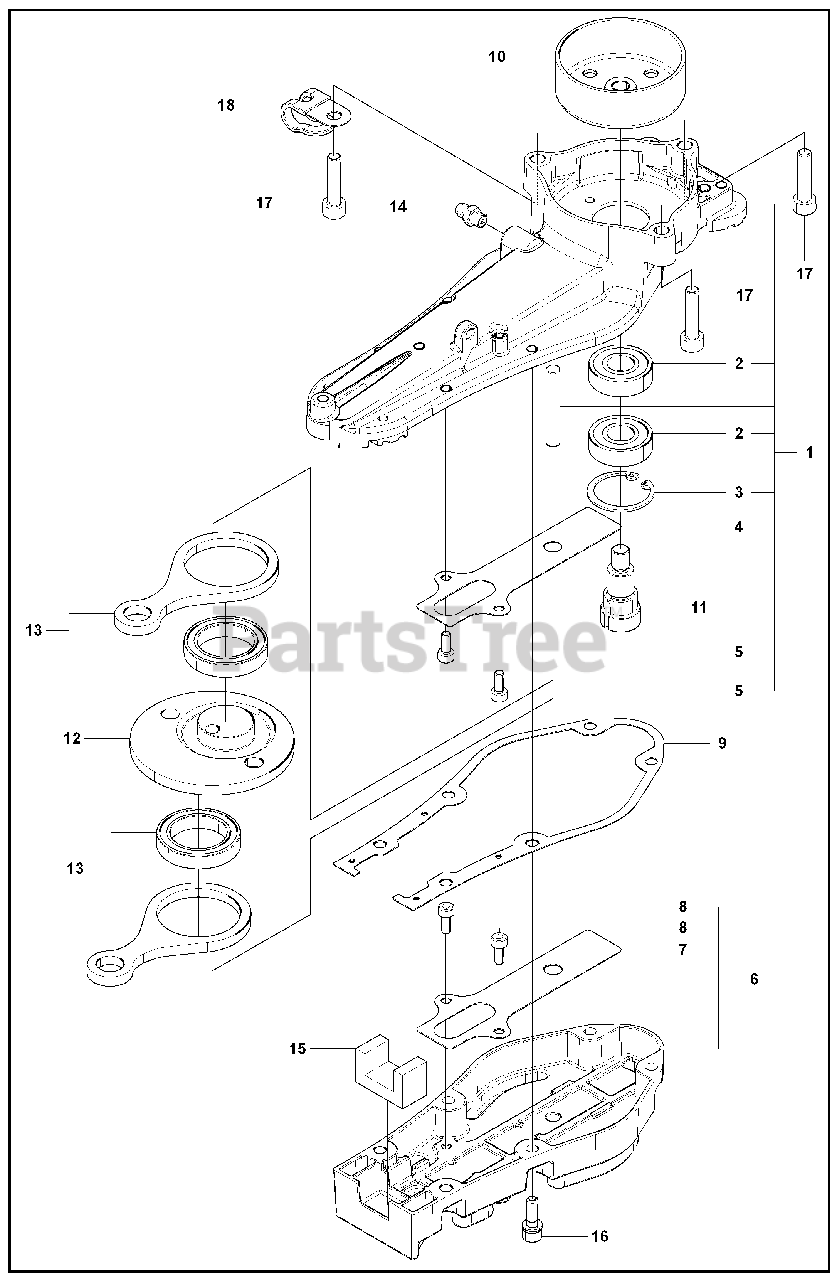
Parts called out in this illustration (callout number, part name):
1	GEARCASE COMP., upper
6	GEARCASE COMP., botom
11	GEAR, drive
12	GEAR, driven
14	FITTING
18	CLAMP
